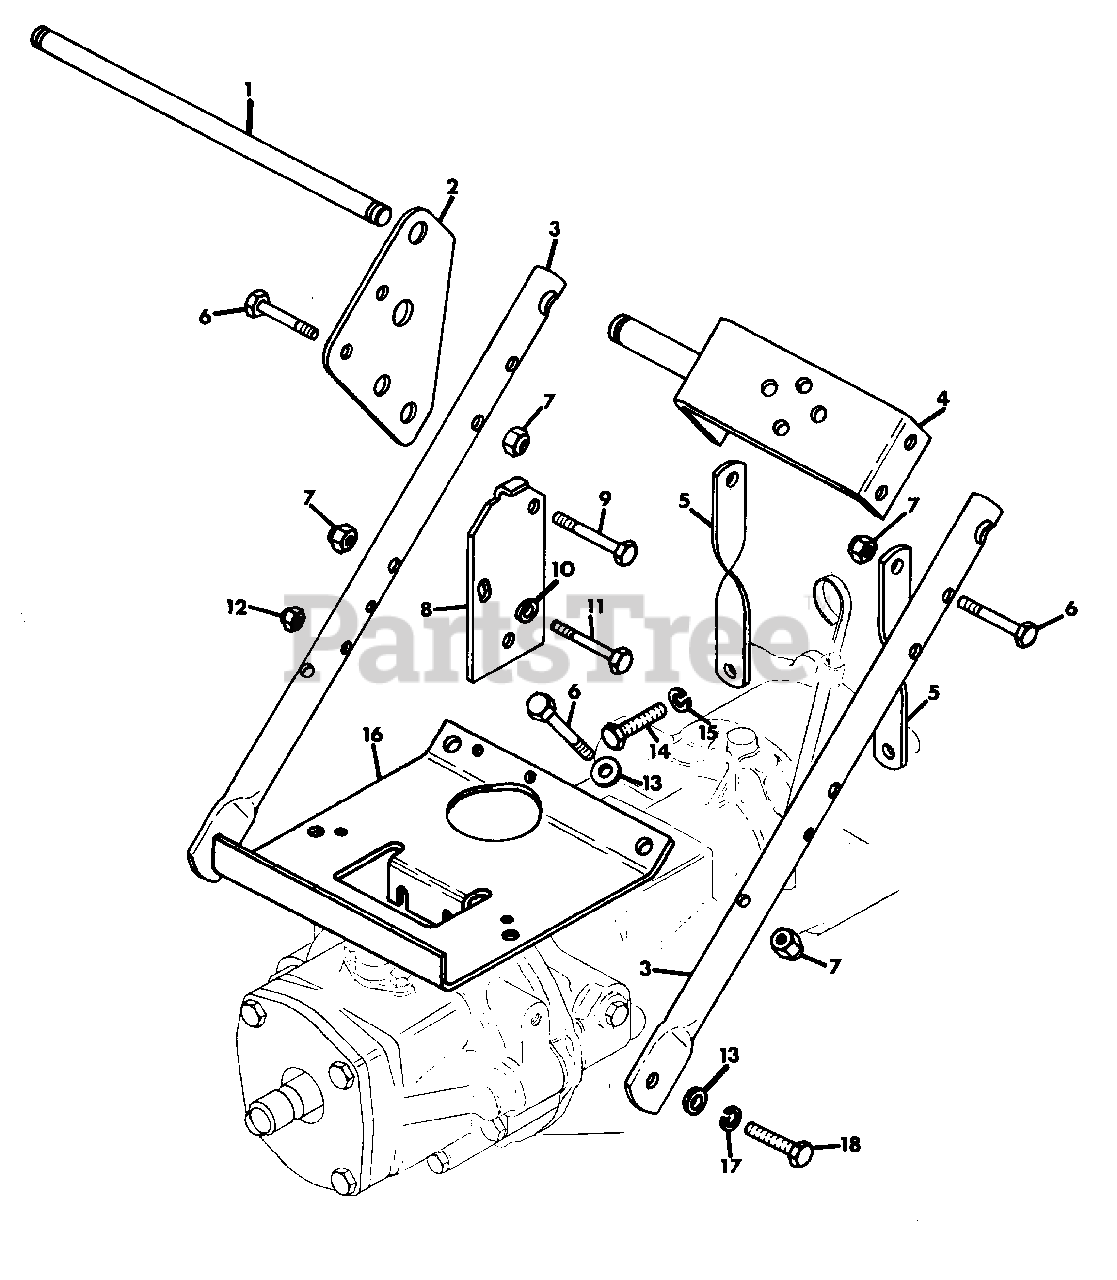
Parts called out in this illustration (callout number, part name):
1	SHAFT CROSS
2	BRACKET, INTERLOCK
3	TUBE, SUPPORT
4	WELDMENT, BRACE
5	BRACE, HANDLE
6	BOLT, HEX 3/8-16X2.25
7	NUT, LOCK 3/8-16
8	BRACKET, HI-LO
9	BOLT, HEX 3/8-16X2.00
10	WASHER, FLAT .281X.625X.065
11	BOLT, HEX 1/4-20X1.75
12	NUT, LOCK 1/4-20
13	WASHER, FLAT .406X.812X.065
14	BOLT, HEX 7/16-14X1.50
15	WASHER, LOCK 7/16
16	BOX, BATTERY
17	WASHER, LOCK 3/8
18	BOLT, HEX 3/8-16X1.38
